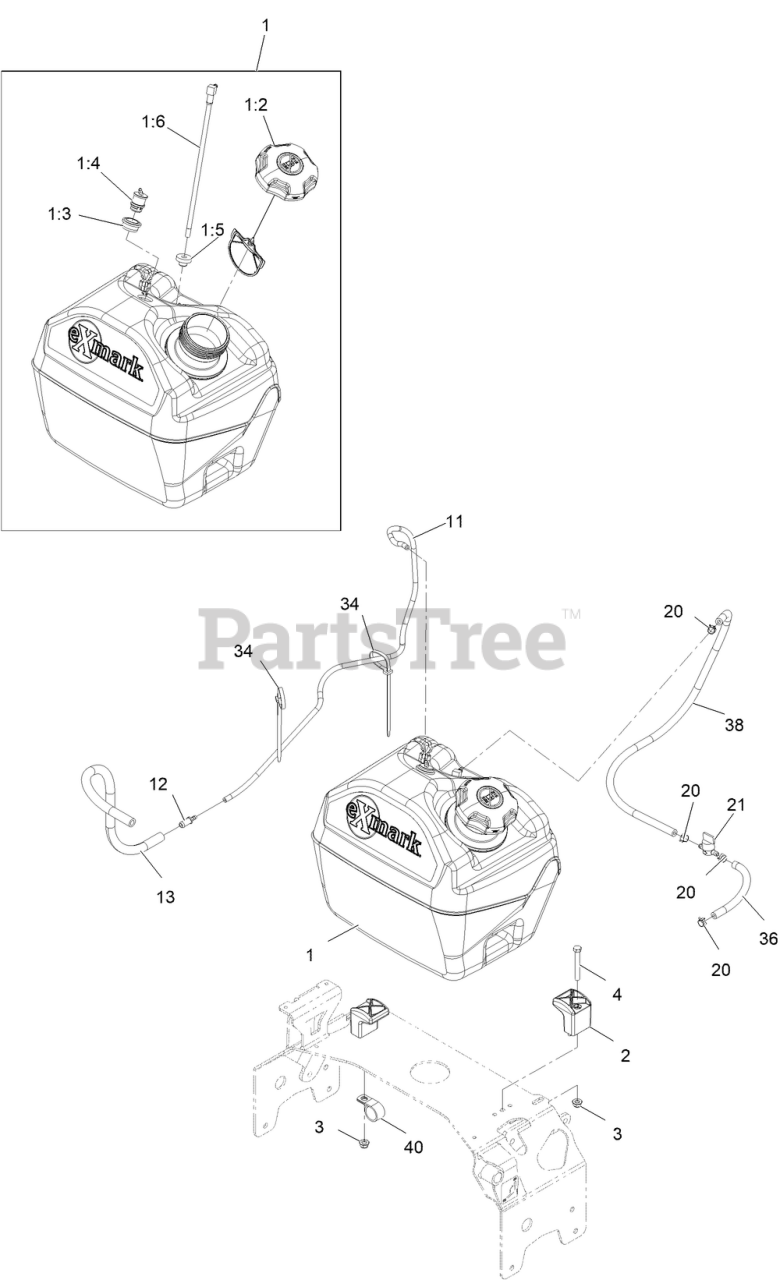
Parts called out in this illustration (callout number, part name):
1	ASM-Fuel Tank, 5 Gal, Exmark
1:2	CAP-FUEL, RATCHETING
1:3	GROMMET
1:4	VALVE-VENT, FUEL
1:5	BUSHING
1:6	FITTING, FUEL W/LINE AND SCREEN
2	CLAMP-TANK
3	NUT-HF, NI
4	SCREW-HH
11	HOSE, EMISSIONS
12	FITTING-STRAIGHT
13	HOSE-FUEL
20	CLAMP-HOSE
21	VALVE-FUEL
34	TIE-CABLE
36	HOSE-FUEL
38	HOSE-FUEL
40	CLIP-LOOM
